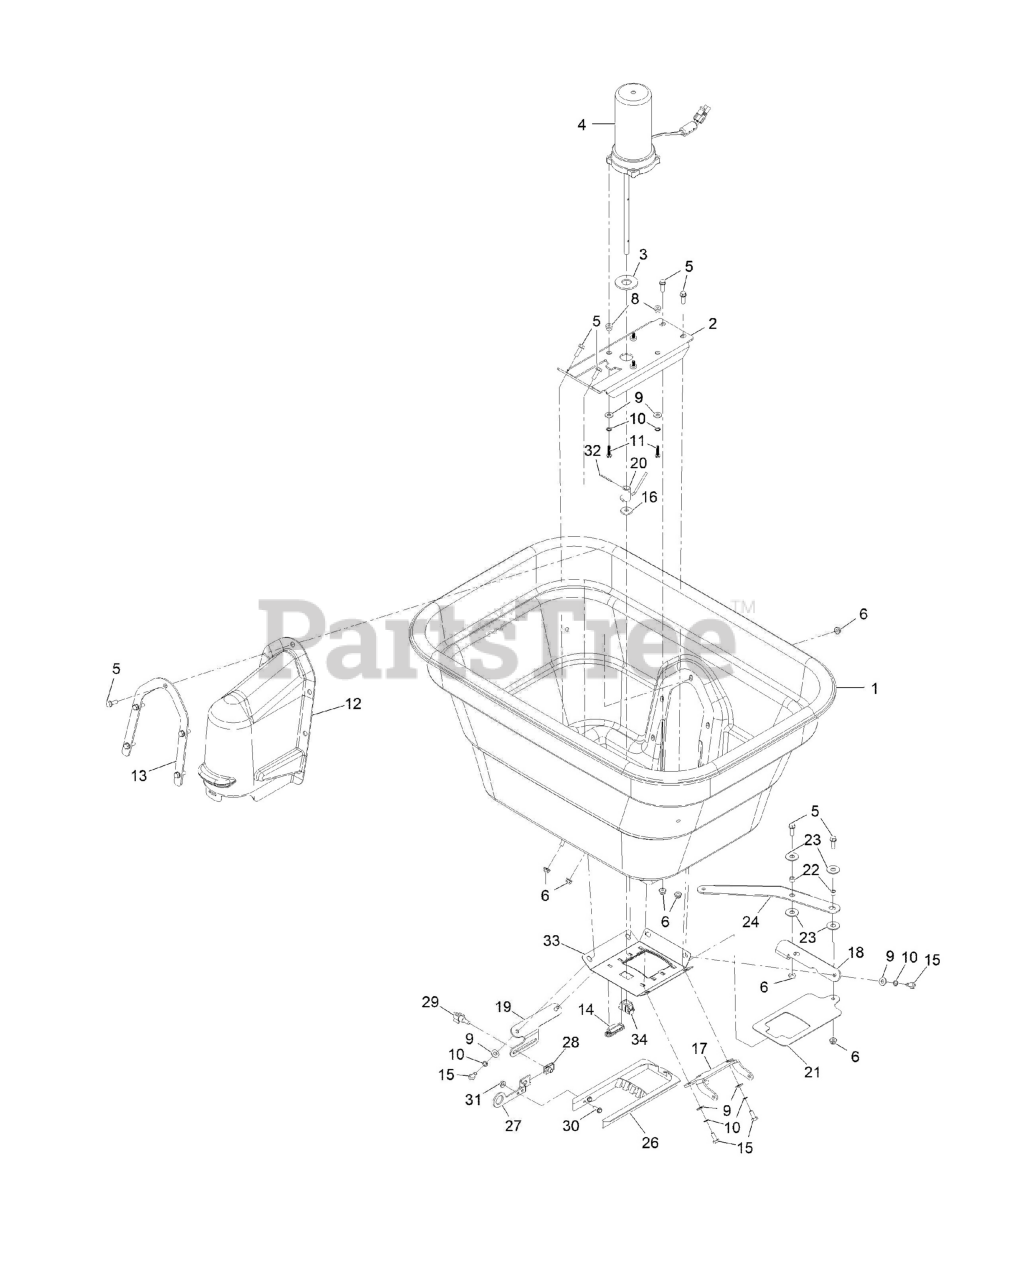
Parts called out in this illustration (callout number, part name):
1	Hopper-Spreader, 175 Lb
2	MOUNT-MOTOR
4	MOTOR-SPREADER
5	SCREW-HWH
8	SPACER-FLANGED
9	WASHER-FLAT
10	WASHER-LOCK, INT
11	SCREW-SHWH
12	COVER-MOTOR
13	SUPPORT-COVER
14	GUIDE-RATE, GATE
15	SCREW-HH
16	WASHER-FELT
17	MOUNT-DEFLECTOR
18	MOUNT-GATE, PIVOT
19	MOUNT-GATE, PIVOT
20	WELD-AGITATOR
21	GATE-SPREADER SEED
24	ARM-ENGAGEMENT
26	DIFFUSER-ACCESSORY
27	BRACKET-ACCUWAY, SLIDE
29	KNOB-STAR, THREE
31	NUT-LOCK, FLANGE
32	Pin-Cotter
33	BOTTOM-MULCH
34	HOPPER BOTTOM BEARING
